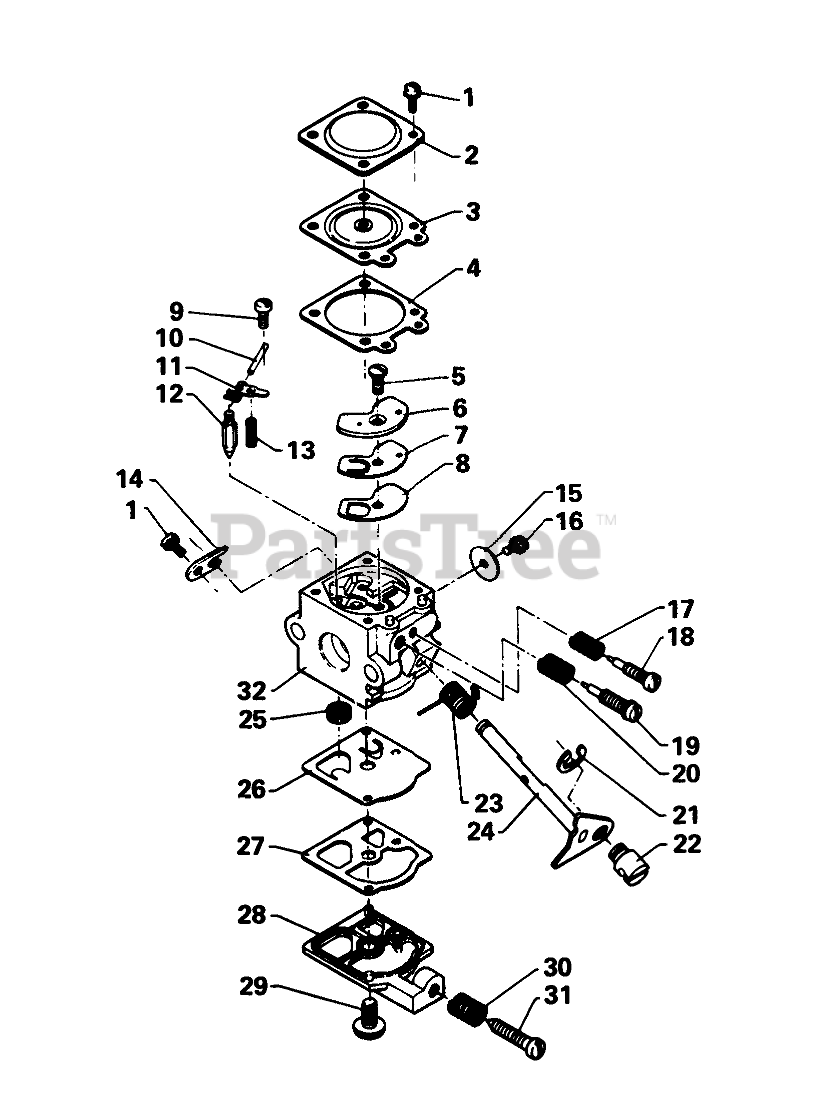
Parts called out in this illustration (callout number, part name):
1	Screw
2	Cover, Diaphragm
3	METERING DIAPHRAGM
4	Gasket, Diaphragm
5	Screw-Circuit Plate
6	Plate, Circuit
7	Diaphragm Circuit Plate
8	Gasket-Circuit Plate
9	Screw-Metering Pin
10	Metering Lever Pin
11	Lever Metering
12	INLET NEEDLE VALVE
13	Spring, Lever
14	Clip Throttle Shaft
15	Valve, Throttle
16	Screw
17	Spring, Needle
18	Needle, Idle
19	Needle, HS
20	Spring, HS Needle
22	Swivel
23	Spring-Throttle Lever
24	THROTTLE SHAFT ASM
25	Screen Inlet
26	Diaphragm Fuel Pump
27	PUMP GASKET
28	Cover, Fuel Pump
29	Screw
30	Spring, Idle Screw
31	Screw, Idle Adjust
32	Body, Carburetor
